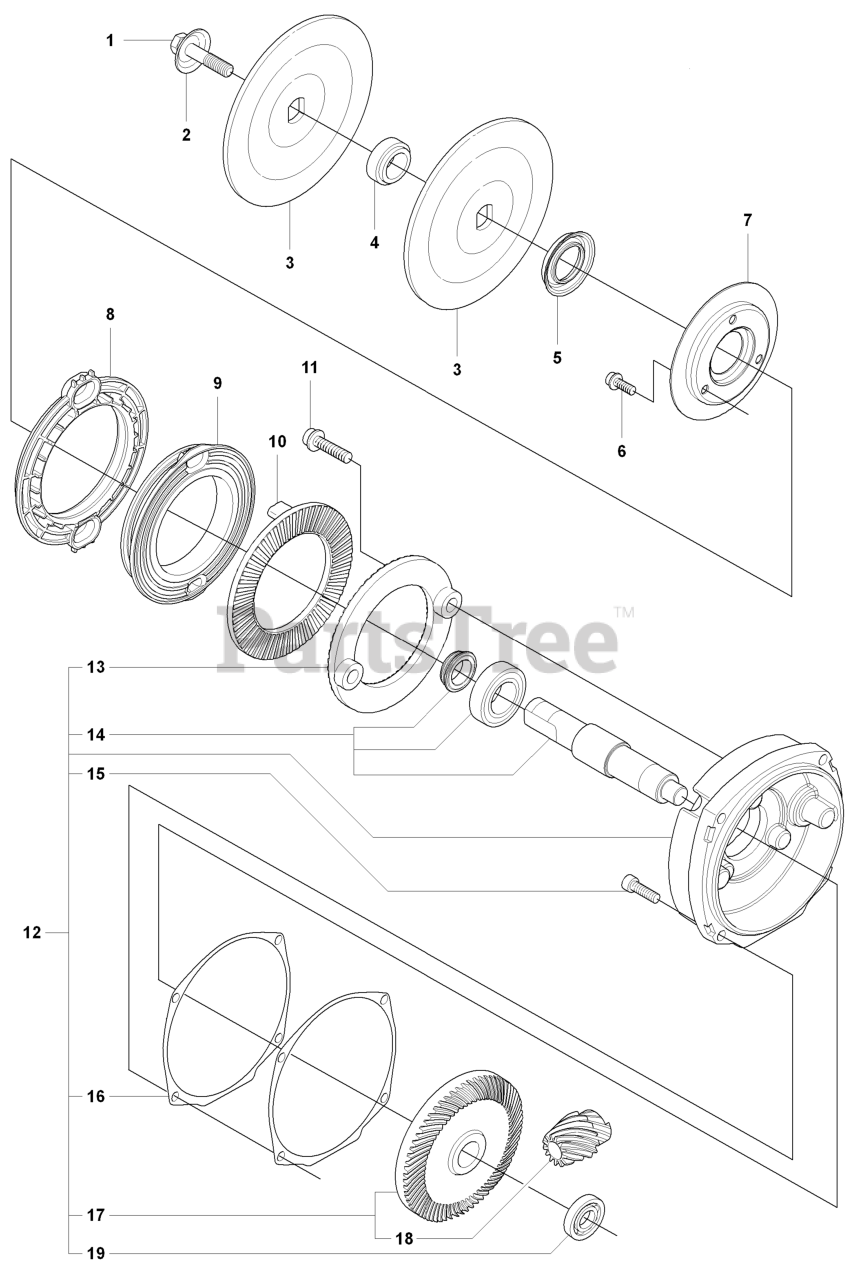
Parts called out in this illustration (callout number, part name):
1	SCREW
2	WASHER
4	BUSHING
4	BUSHING-30MM
6	SCREW MC6S 5X16
8	DISTANSRING SPRSKYDD
11	SCREW
12	GEAR SET
14	SHAFT
15	SCREW
16	GASKET
17	GEAR CPL.
19	BALL BEARING
